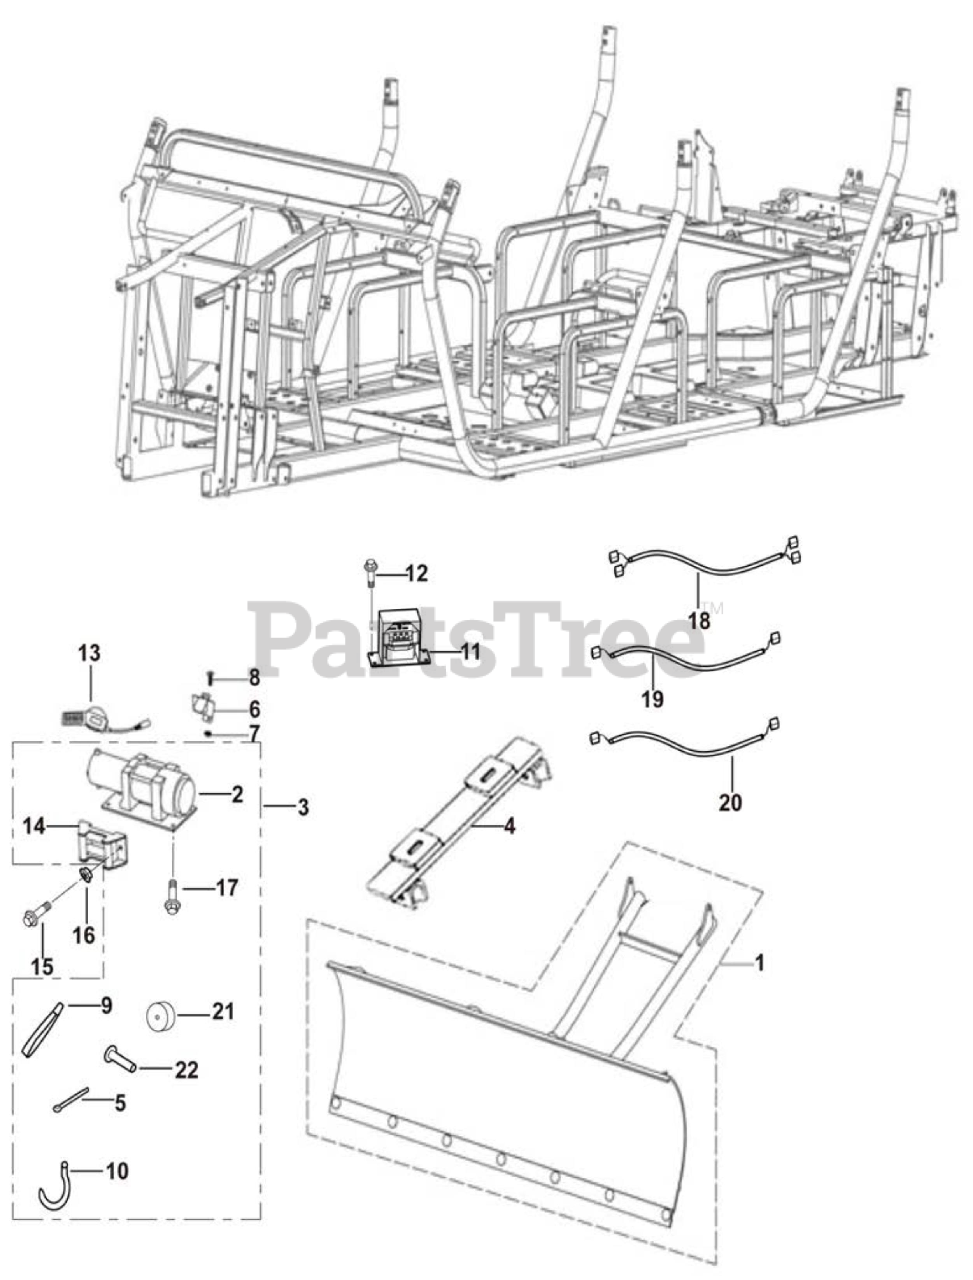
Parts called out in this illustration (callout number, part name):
1	Snow Plow I
1	Snow Plow II
1	Snow Plow III
2	Winch body
3	Winch Assy
4	Snow plow mounting plate
5	Cotter Pin 2.5X30
6	Winch handle plate
7	Hexagon Flange Self-Lock Nuts (With Metallic Insert) M6
8	Cross Large Plate Head Screw M6X16
10	Load hook
11	Winch Relay
12	Flange Bolt M6X16
13	Winch remote control
14	Winch guide pulley
15	Flange Bolt M10X1.25X20
16	Nut M10X1.25
17	Flange Bolt M8X20
18	Winch Motor Wiring
19	Winch Battery Wiring
20	Winch controller leading wiring
21	Plastic clasp
22	Pin 9.5X40
